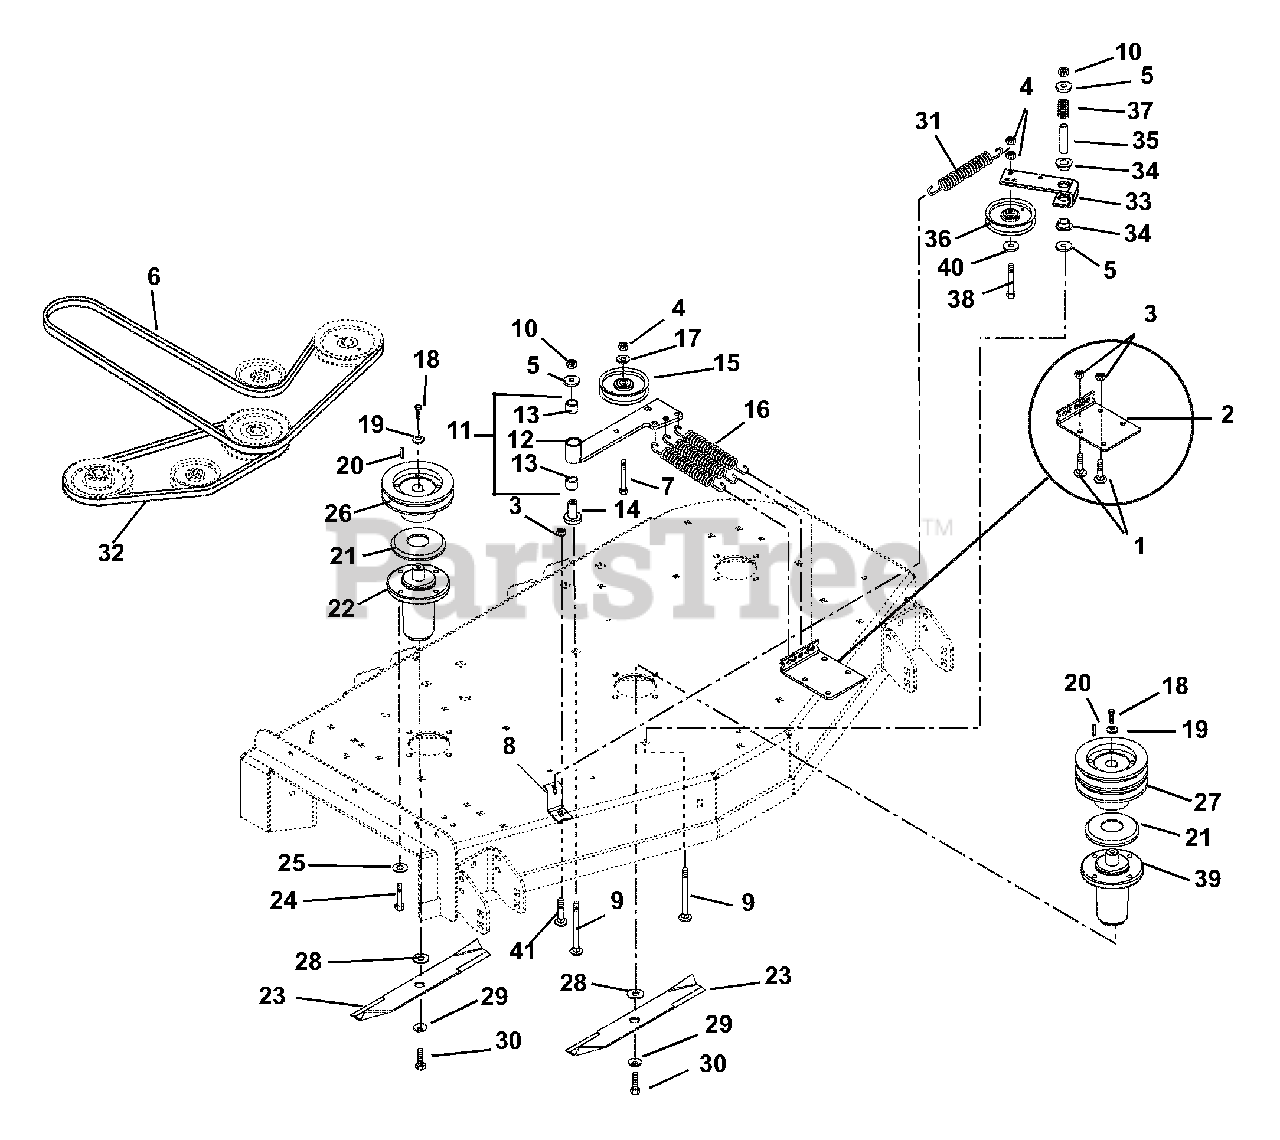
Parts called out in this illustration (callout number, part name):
1	@BLT-RDHDSQNK .38-16X.75 G5YZ
2	BRACKET,LONG SPRING (DIESEL)
3	@NUT-LK-TOP-FLG .38-16 YWZC
4	@NUT-LK-CTR .38-16 YWZC
5	@WSHR-FL-STL.50X1.25X.083 YWZC
6	V-BELT, HB-WRAPPED
7	@BLT-RDHDSQNK .38-16X2.75 G5YZ
8	ANCHOR, SPRING (RED)
9	@BLT-RHDSSQNK .50-13X3.50 G5YZ
10	@NUT-LK-TOP-FLG .50-13 YWZC
11	ASSY-DECK IDLER PIVOT ARM
12	WMT, DECK IDLER PIVOT ARM
13	BRG, 1.00 X 1.12 X .75
14	BEARING, PEDESTAL
15	IDLER-FLAT 4.00 X .38 (2.32W)
16	SPRING, EXT0NSION DIA1.0X6.0LG
17	WSHR-FL-STL .375X1.125X.065YWZ
18	BLT-HEX .38-16X1.00 YZ GR8
19	WASHER, CUPPED SERRATED, .375
20	KEY, SQ .25X.25X1.00 RC 40-50
21	SLINGER, DUST
22	ASM,MAINT FREE SPINDLE
23	BLADE 60" MOWER CE
23	BLADE, MULCHING (20.50")
24	@BLT-HEX .38-16X1.00 GR5 YWZC
25	@WSHR-LK .38X.094 REG YWZC
26	WELDMENT, SPINDLE SHEAVE 6.00
27	SHEAVE, DOUBLE (6.25")
28	WSHR-FLT .640X1.75X.250 YWZC
29	WSHR-BLVL .669X1.535X.138
30	BLT-HEX .62-18X1.75 GR8 YWZC
31	SPRING, EXT
32	V-BELT, HB-RAW EDGE
33	ARM,IDLER PIVOT
34	BSHG-FLG .762X1.0X.580X1.48 NY
35	SPACER .560X.750X2.437 ST
36	V-IDLER, 4.00X.38
37	SG-COMP .085X.80X1.00 WLD36
38	@BLT-HEX .38-16X2.25 GR5 YWZC
39	ASM,MAINT FREE SPINDLE
40	@WSHR-FL-STL.406X.812X.065 YWZ
41	@BLT-RDHDSQNK .38-16X1.00 G5YZ
